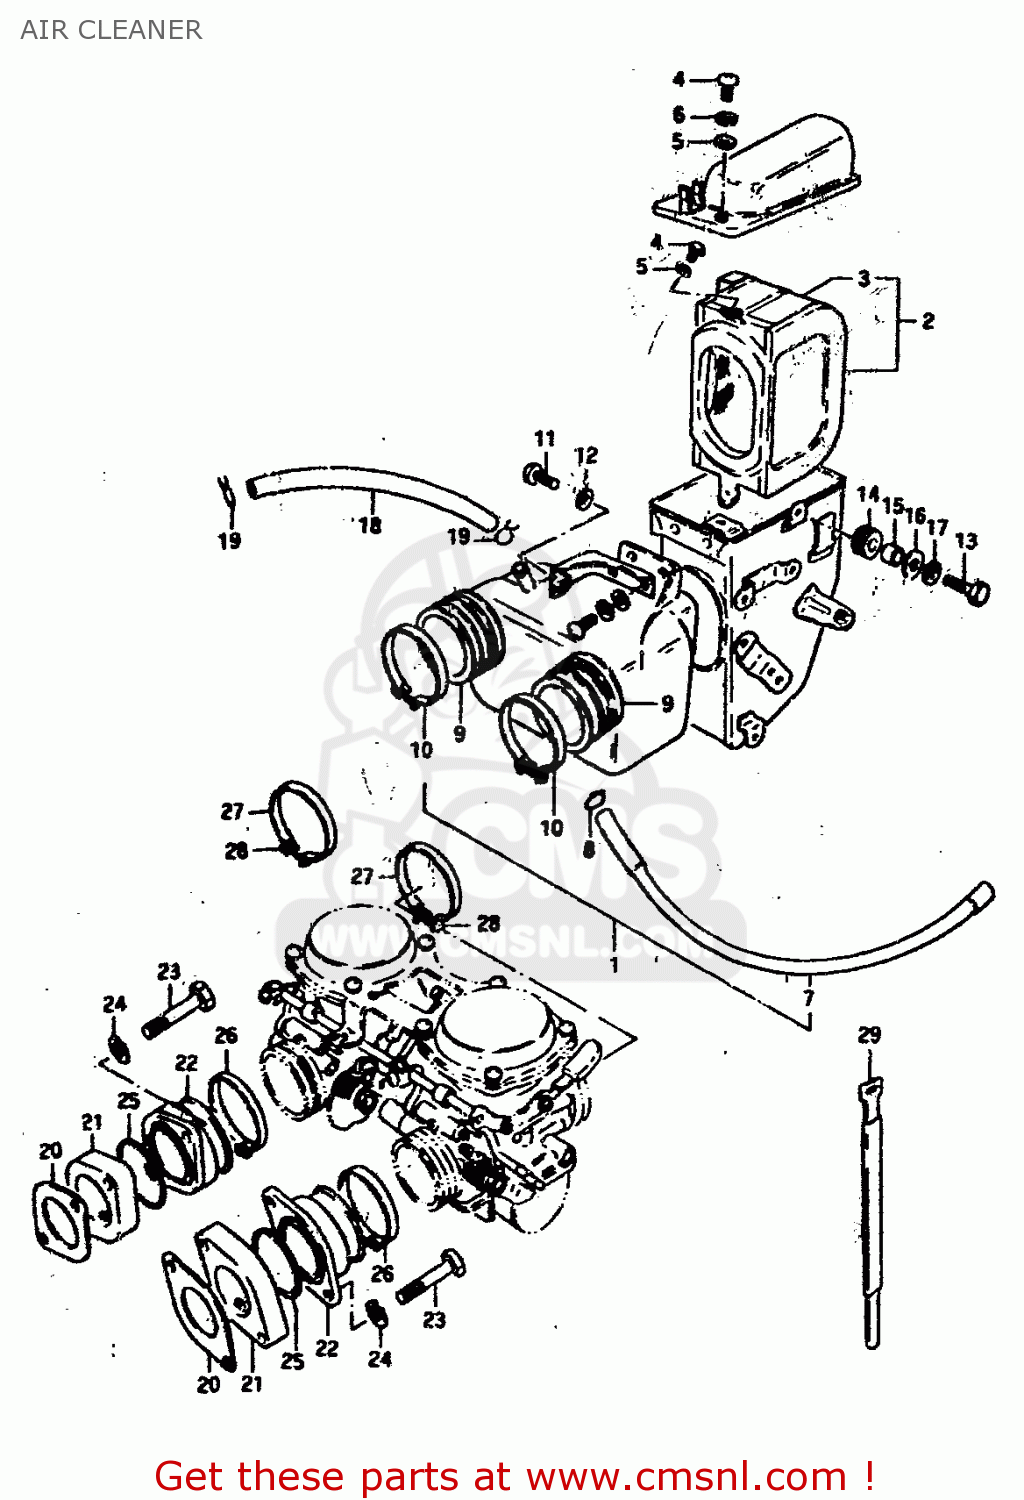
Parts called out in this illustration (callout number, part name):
1	CLEANER ASSEMBLY,AIR
2	FILTER ASSY
3	FILTER
4	SCREW
5	WASHER
6	LOCK WASHER
7	HOLDER,FILTER
8	HOSE,AIR CLEANER
9	HOSE,AIR CLEANER INLET
10	CLAMP
11	SCREW
12	WASHER
13	BOLT
14	CUSHION
15	SPACER (6.1X9X9)
16	WASHER
17	LOCK WASHER
18	HOSE
19	CLIP
20	GASKET,CARBURETOR (NAS)
21	INSULATOR,CARBURETOR
22	PIPE,INTAKE
23	BOLT
24	LOCK WASHER
25	O-RING (D:2.4 ID:39.7)
26	CLAMP
27	CLAMP
28	SCREW
29	CLAMP
